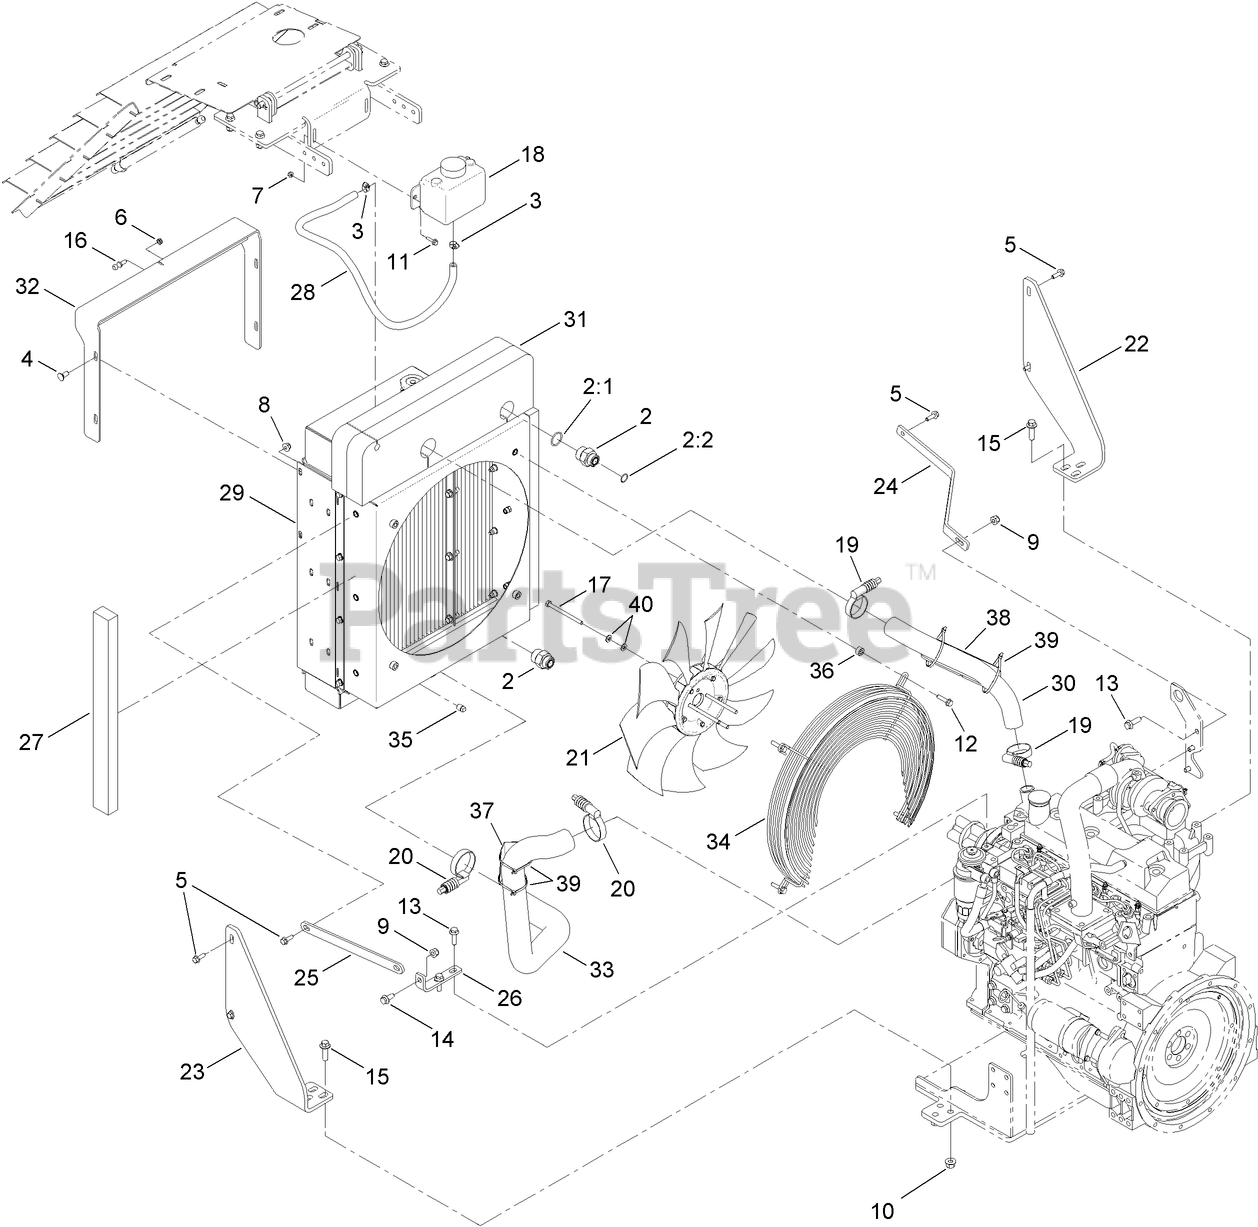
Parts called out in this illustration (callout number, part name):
2	FITTING-STR
2:1	O-RING
2:2	O-RING
3	CLAMP-WORM
4	BOLT-CARR
5	SCREW-HHF
6	NUT-LOCK, NI
7	NUT-HF
8	NUT-HF, NI
9	NUT-LOCK, NI
10	NUT-LOCK, HHF
11	SCREW-HHF
12	SCREW-HHF
13	SCREW-HHF
14	SCREW-HHF
15	SCREW-HHF
16	STUD-BALL
17	SCREW-HH
18	TANK-Overflow
19	CLAMP-TORQUE, CONSTANT
20	CLAMP-TORQUE, CONSTANT
21	FAN-19 INCH (10-BLADE)
22	BRACKET-MOUNT, RADIATOR
23	BRACKET-MOUNT, RADIATOR
24	STRAP-RADIATOR
25	STRAP-RADIATOR
26	PLATE-MOUNT, STRAP
27	SEAL-FOAM
28	HOSE-COOLANT, OVERFLOW
29	COOLER ASM
30	HOSE-UPPER, RADIATOR
31	FOAM-RADIATOR, UPPER
32	SHOCK MOUNT ASM
33	HOSE-LOWER, RADIATOR
34	GUARD-Fan
35	PLUG-PIPE, SQH
36	SPACER-NOMINAL, 10.5mm
37	PROTECTOR-HOSE
38	PROTECTOR-HOSE, 8 INCH
39	TIE-CABLE
40	WASHER-PLAIN
